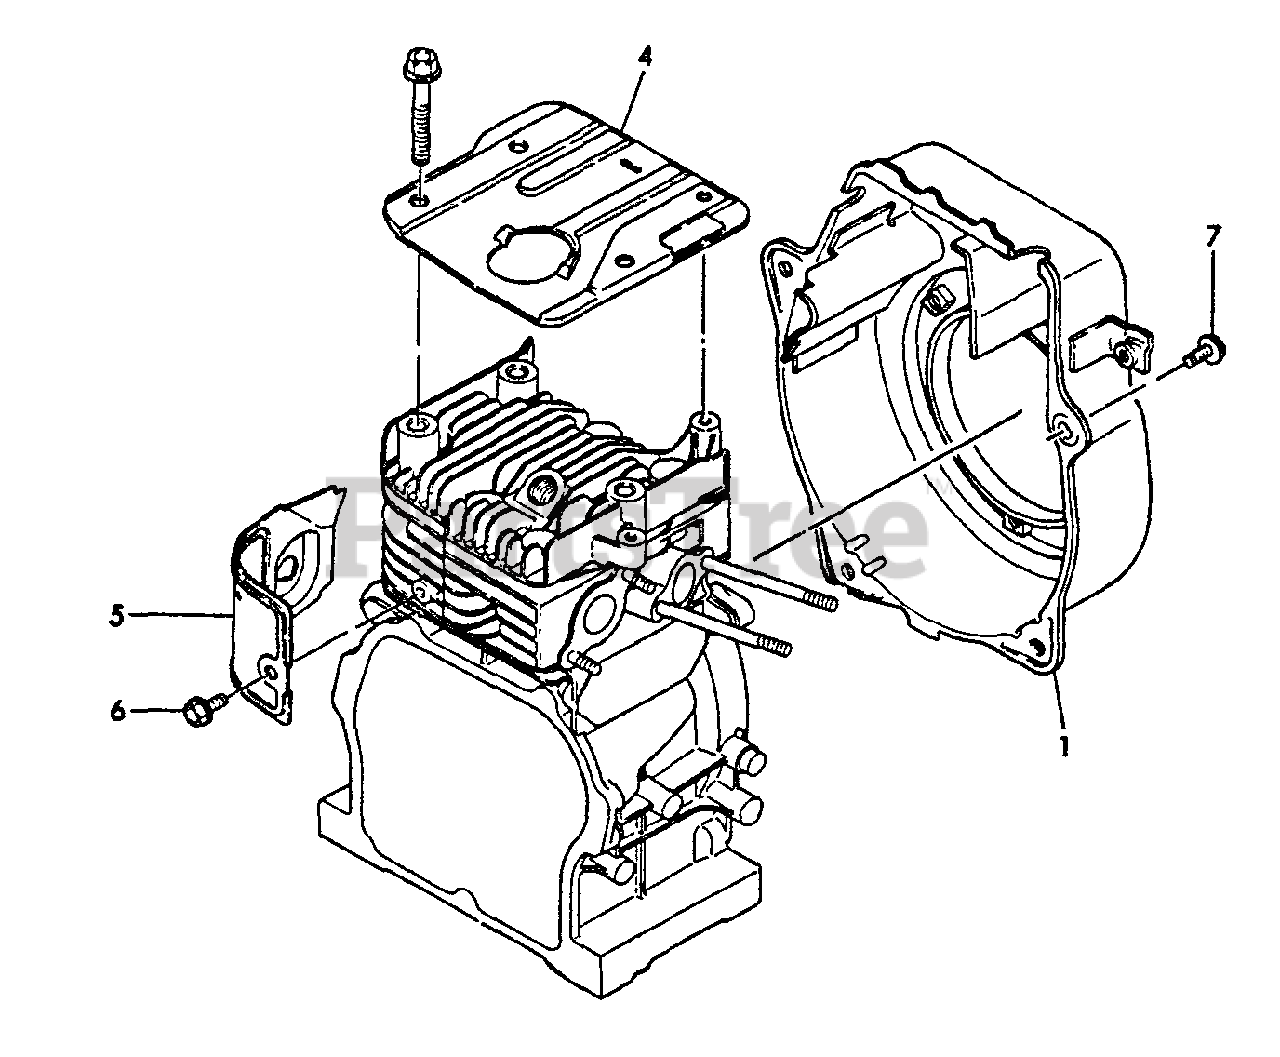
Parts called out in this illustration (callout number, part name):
1	COVER, FAN
4	COVER, CYLINDER HEAD
5	SHIELD, CYLINDER
6	BOLT - 6X8 -- PLATED
7	BOLT - 6X8 -- PLATED
